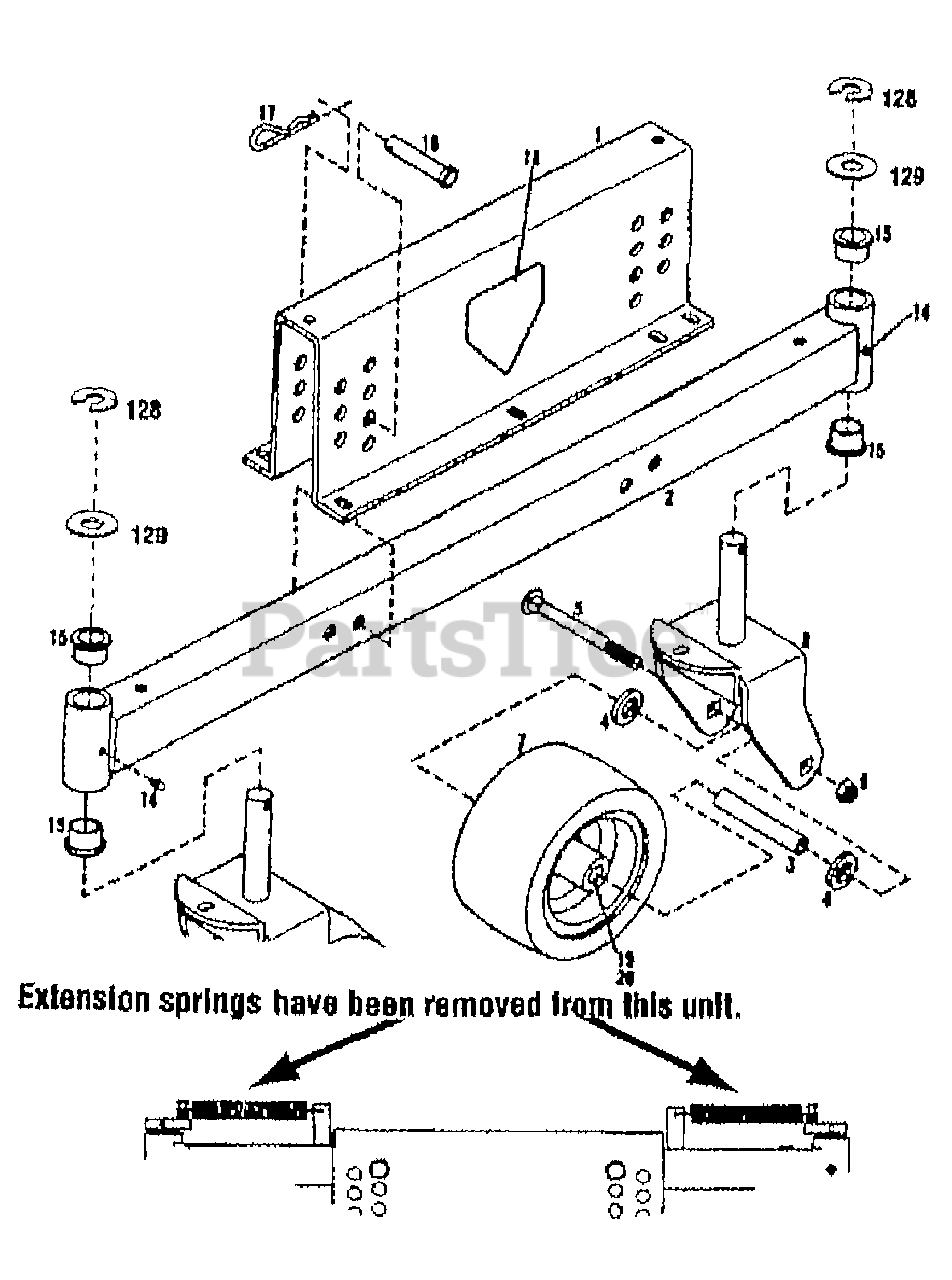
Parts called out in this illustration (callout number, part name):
1	MOUNT-GAGE WHEEL W/DECALS
3	SLEEVE-WHEEL
4	WASHER-1.5X.812X.134 ZP
5	ASSM-WHEEL SUPPORT
5	SCR-CARR 1/2-13X4.75
6	NUT-TOP LOCK 1/2-13 ZP
7	ASSM-TIRE&WHEEL 6.25X3.
8	ASSM-WHEEL YOKE
14	FITTING-GREASE 1/4-28X2.00
15	BEARING-FLANGE
16	PIN-CLEVIS .62X2.50 ZP
17	PIN-HITCH .149DIA
18	DECAL-OPEI CAUTION
19	BEARING-ROLLER
20	CAP-BEARING
128	RING-HEAVY EXT HD 1.0 ID
129	WASHER-THRUST
